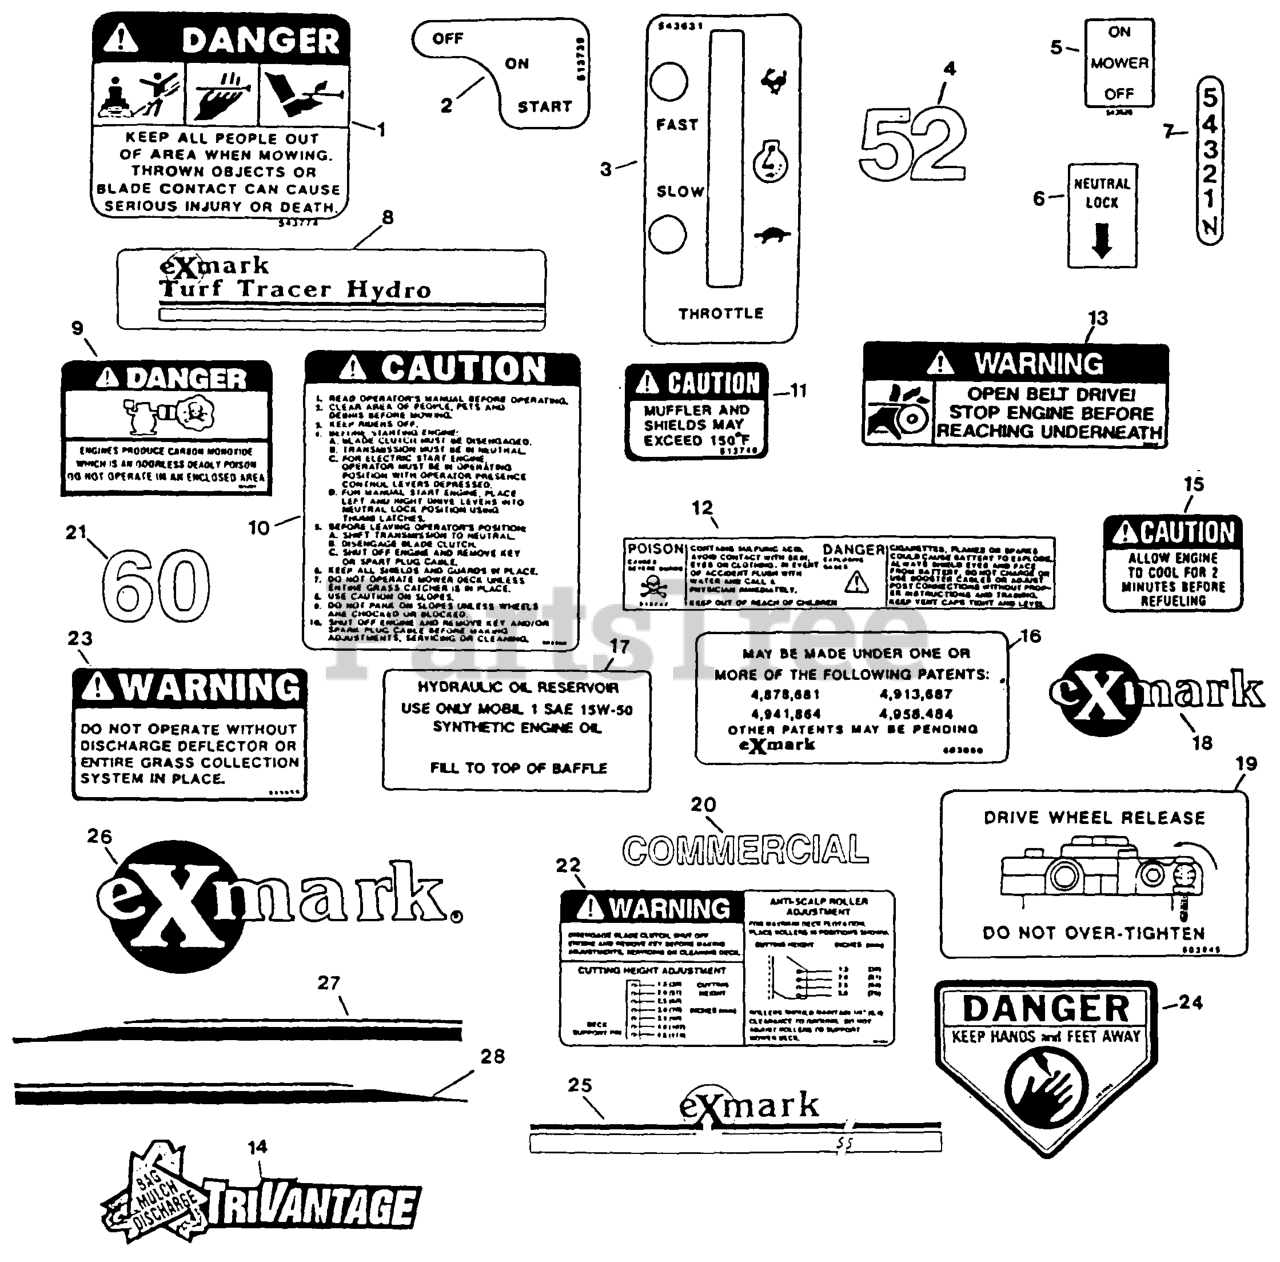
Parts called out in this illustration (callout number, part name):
1	DECAL-DANGER
5	DECAL-MOWER SWITCH
6	DECAL,NEUTRAL LOCK
7	DECAL - SHIFTER
12	DECAL-BATTERY
13	DECAL,BELT DRIVE
17	DECAL,HYD TANK
19	DECAL,DRIVE RELEASE
23	DECAL-WARNING, DISCHARGE
24	DECAL-DANGER
26	NUT,PUSH
